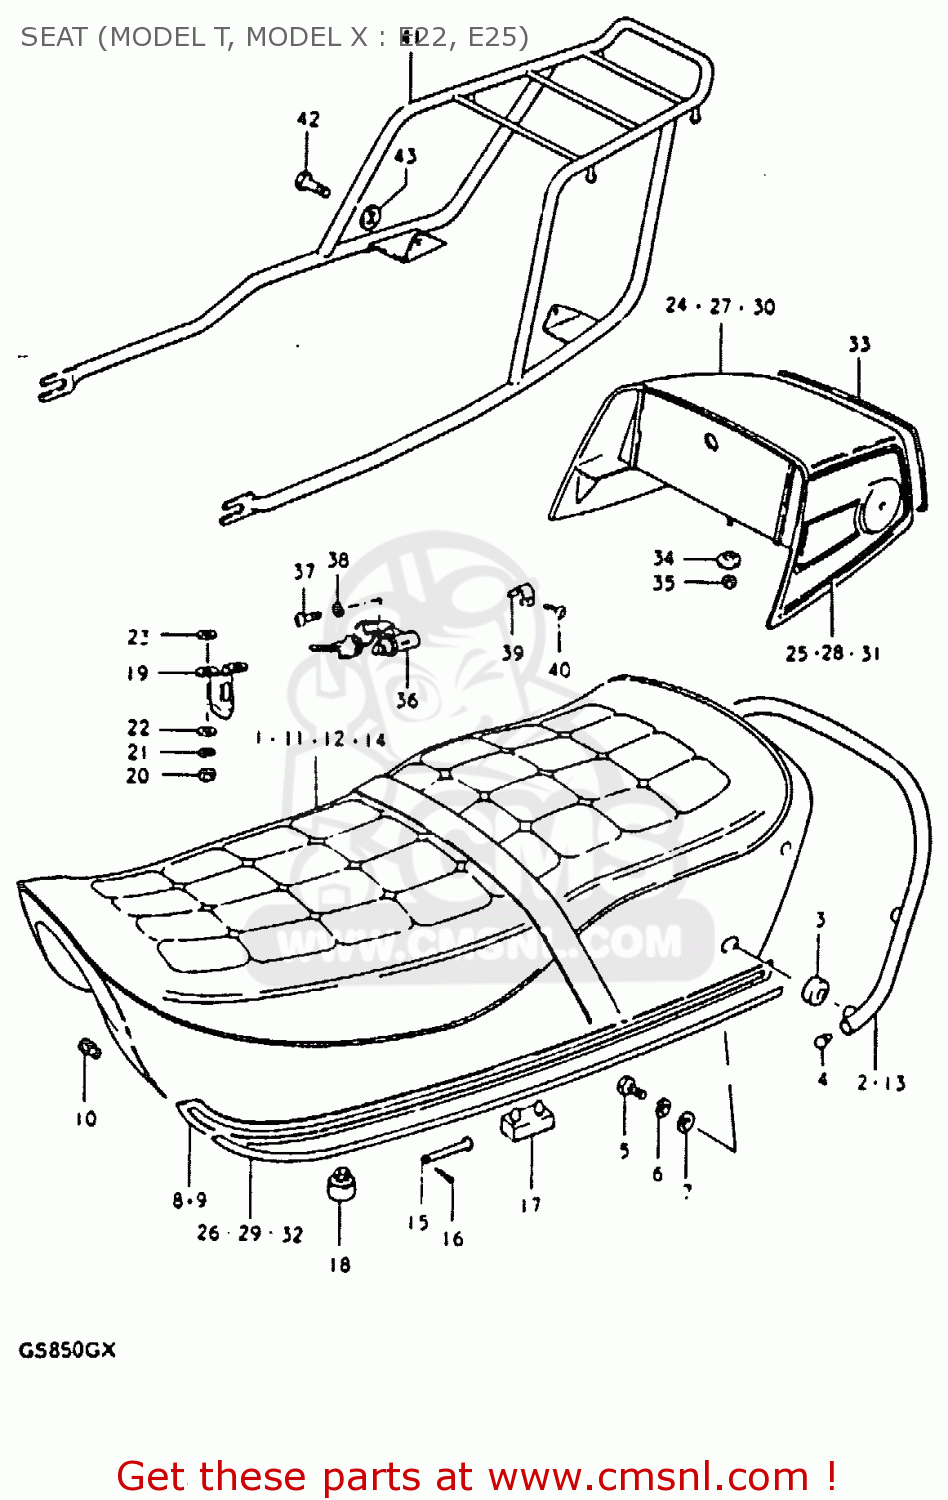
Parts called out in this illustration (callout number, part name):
3	CUSHION
4	END,SHEET HANDLE
5	BOLT
6	LOCK WASHER
7	WASHER
8	MOLE,R
9	MOLE,L
10	NUT
11	SEAT ASSY (FLAT TYPE)
12	SEAT ASSY
13	HANDLE, PILLION RIDER
15	PIN
16	PIN
17	CUSHION
18	CUSHION
19	STRIKER,SEAT LOCK
20	NUT
21	LOCK WASHER
22	WASHER
23	WASHER (6.5X20X1.2)
24	COVER, SEAT TAIL
25	TAPE SET
26	TAPE SET
27	COVER, SEAT TAIL
28	TAPE SET
29	TAPE SET, SEAT MOULDING
30	COVER, SEAT TAIL
31	TAPE SET
32	MOULDING TAPE SET
33	MOLDING,SEAT TAIL COVER
34	WASHER
35	NUT 6MM
36	LOCK ASSY,SEAT
37	SCREW
38	LOCK WASHER
39	SPRING,HELMET HOLDER
40	SCREW
41	CARRIER
42	BOLT
43	WASHER
